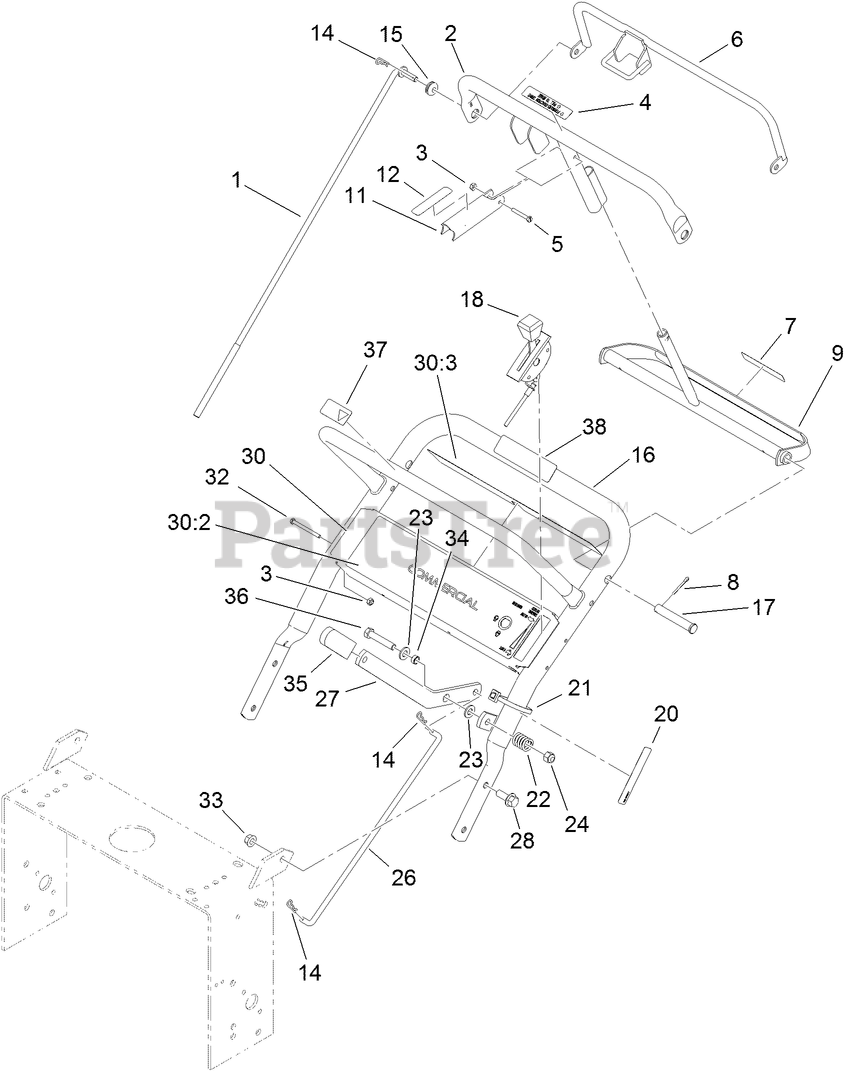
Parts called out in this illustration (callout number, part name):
1	ROD-CONTROL
2	BAR-CONTROL
3	NUT-LOCK, NI
4	DECAL
5	SCREW-SHH
7	DECAL
8	PIN-COTTER
9	CONTROL-PIVOT
11	LEVER-BRAKE, PARKING
12	DECAL
14	PIN-COTTER
15	GROMMET-RUBBER
16	HANDLE-UPPER
17	PIN-CLEVIS
18	CABLE-THROTTLE
20	DECAL-ENGAGE, DECK
21	TIE-PLASTIC
22	SPRING-COMPRESSION
23	WASHER-FLAT
24	NUT-HF, NI
26	LINKAGE-DRIVE, BLADE
27	LEVER-ENGAGEMENT, BLADE
28	SCREW-HHF
30	CONTROL PANEL ASM
30:2	DECAL-PANEL, CONTROL
30:3	DECAL-DANGER
32	SCREW-SHH
33	NUT-HF
34	SPACER
35	GRIP-LEVER
36	SCREW-HH
37	DECAL-PROTECTION, EAR
38	DECAL-ARRESTER, SPARK
